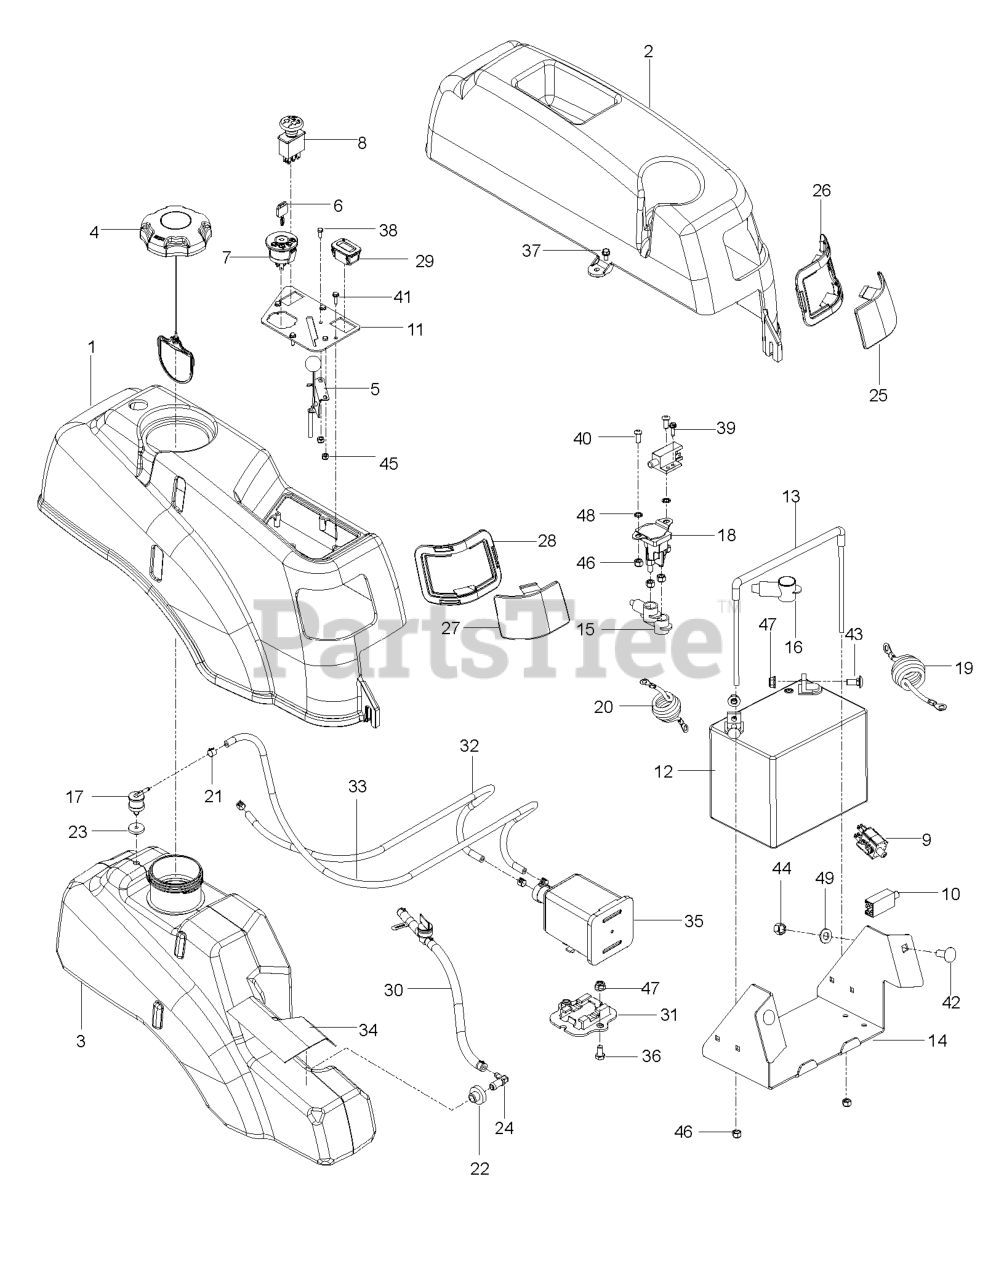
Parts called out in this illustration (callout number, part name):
1	FENDER, RT, GRAY
2	FENDER, LT, BLK
3	TANK, FUEL, RT-EPA
4	CAP, FUEL
5	CABLE, THROTTLE
6	KEY
7	RP IGNITION SWITCH
8	RP.SWITCH, BLADE
9	SWITCH, BRAKE 3P
10	SWITCH, INTERLOCK
11	PLATE.CONTROL.CONSOLE.BLACK
12	BATTERY, 12 V 330 AMP
13	BATTERY TIE DOWN ASSEMBLY
14	BOX, BATTERY, BLACK
15	TERMINAL COVER-SM
17	VALVE.FUEL.CHECK
19	BATTERY CABLE, NEGATIVE
20	CABLE POSITIVE, LONG
21	CLAMP, HOSE
22	RUBBER GROMMET
23	GROMMET, CHECK VALVE
24	STEM, FUEL TANK
25	LENS, COLORED LEFT
26	LEFT HEADLIGHT RIM GREY
27	LENS, COLORED RIGHT
28	RT HEADLIGHT RIM GREY
29	HOUR METER
30	FUEL LINE ASSY
31	BRACKET, CANISTER
32	HOSE, VAPOR 3/16 X 39"
33	HOSE, VAPOR 3/16 X 30"
34	SHIELD, HEAT
35	CANNISTER, CARBON
36	HCS 5/16-18 X 5/8 GR 5 ZD
37	BOLT 1/4-20 X 1/2 HWST
38	HCS #10-24 X 1/2
39	SCREW #10 X 1/2 SELF TAPPING
40	SCR 1/4-20 X 5/8 BTN SKT HD ZD
41	SCR #10-12X3/4 HEX WAS HD ZD
42	RHSNB 3/8C X 1
43	BOLT 5/16C X 3/4" CARRIAGE
44	NUT 3/8-16 NYLOC
45	NUT 10-24 NYLOC
46	NUT.1/4-20.HEX.NYLOC.ZD
47	5/16-18 NYLOC FLANGE NUT
48	WASHER 1/4 INT TOOTH
49	WASHER 3/8 SAE FLAT
